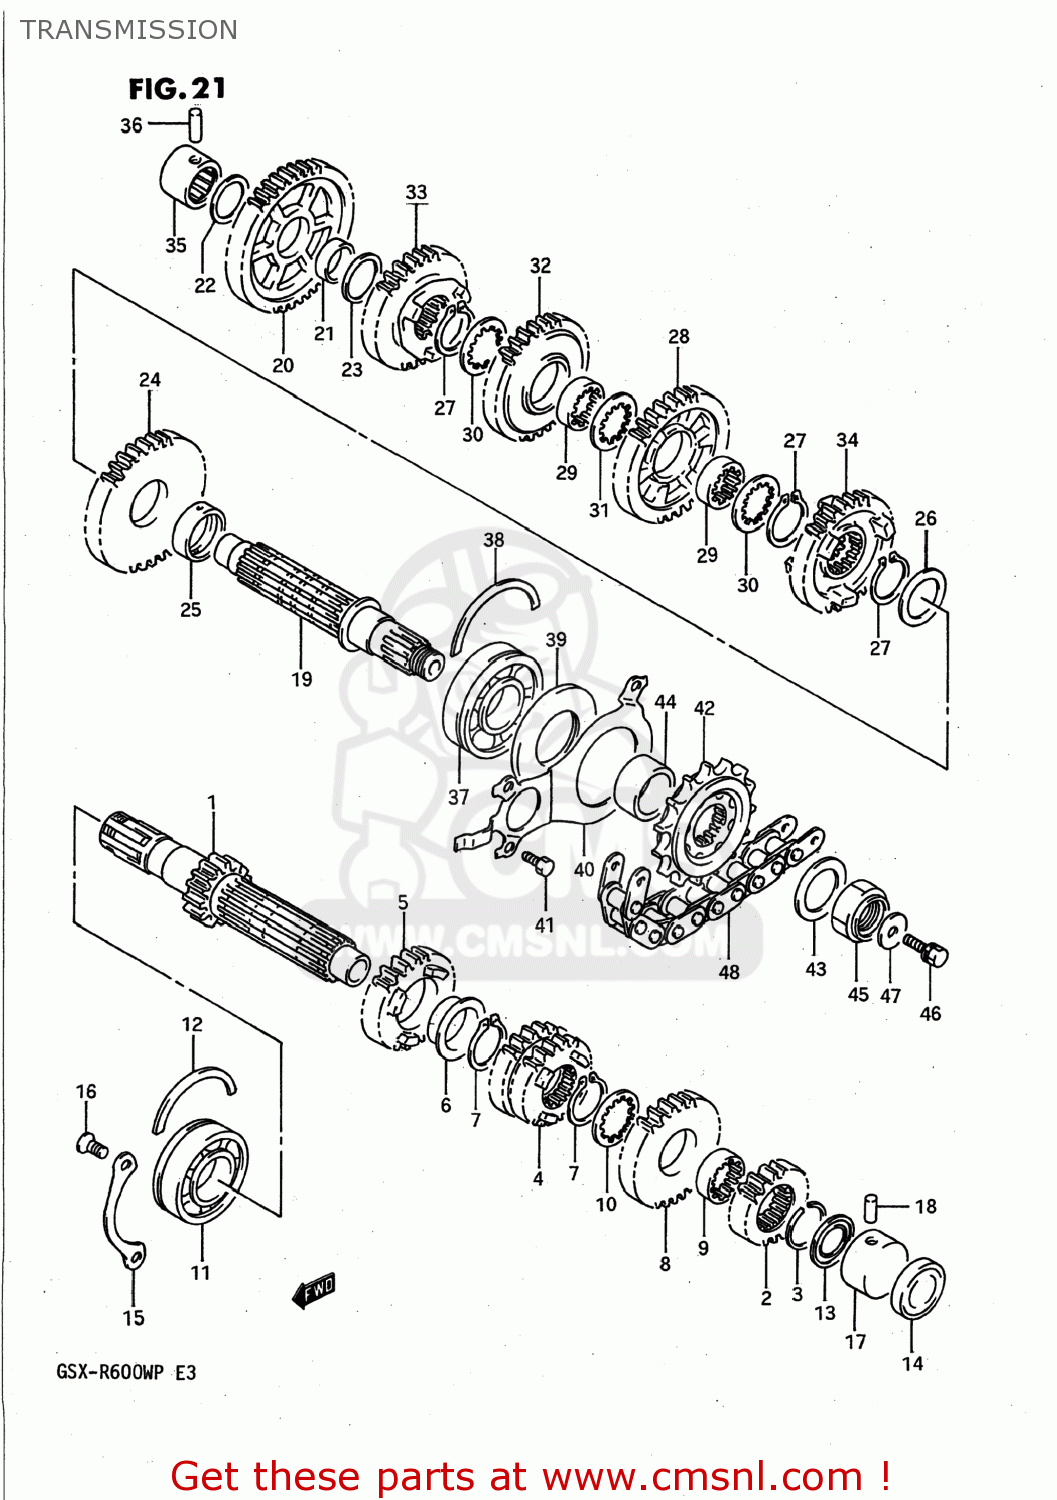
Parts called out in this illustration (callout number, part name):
1	SHAFT,COUNTER
2	GEAR,SECOND DRIVE
3	CIRCLIP
4	GEAR,THIRD & FOURTH DRIVE
5	GEAR,FIFTH DRIVE
6	BUSH(28X32X2)
7	CIRCLIP
8	GEAR,SIXTH DRIVE
9	BUSHING,SIXTH DRIVE GEAR
10	WASHER,LOCK
11	BEARING(25X62X17)
12	C-RING
13	SEAL,OIL(20X31.2X2.7)
14	CAP,COUNTER SHAFT,L
15	RETAINER,CNTR SHAFT BEARING
16	SCREW
17	BEARING(20X34X17.5)
18	PIN
19	SHAFT,DRIVE
20	GEAR,1ST DRIVEN(NT:43)
21	BUSH(22X26X9)
22	WASHER
23	WASHER
24	GEAR,SECOND DRIVEN
25	BUSHING
26	WASHER, THRUST
27	CIRCLIP
28	GEAR,3RD DRIVEN(NT:33)
29	BUSH,3RD DRIVEN GEAR
30	WASHER,LOCK
31	WASHER,LOCK
32	GEAR,FOURTH DRIVEN
33	GEAR,5TH DRIVEN(NT:29)
34	GEAR,SIXTH DRIVEN
35	BEARING(20X34X20)
36	PIN
37	BEARING(28X70X18)
38	C RING
39	SEAL,OIL(34.8X70X6)
40	RETAINER,DRIVE SHAFT OIL SEAL
41	BOLT
42	SPROCKET,ENGINE
43	WASHER,THRUST
44	SPACER(25X36X17.7)
45	NUT
46	BOLT
47	WASHER
48	CHAIN ASSEMBLY,DRIVE 50GSV
